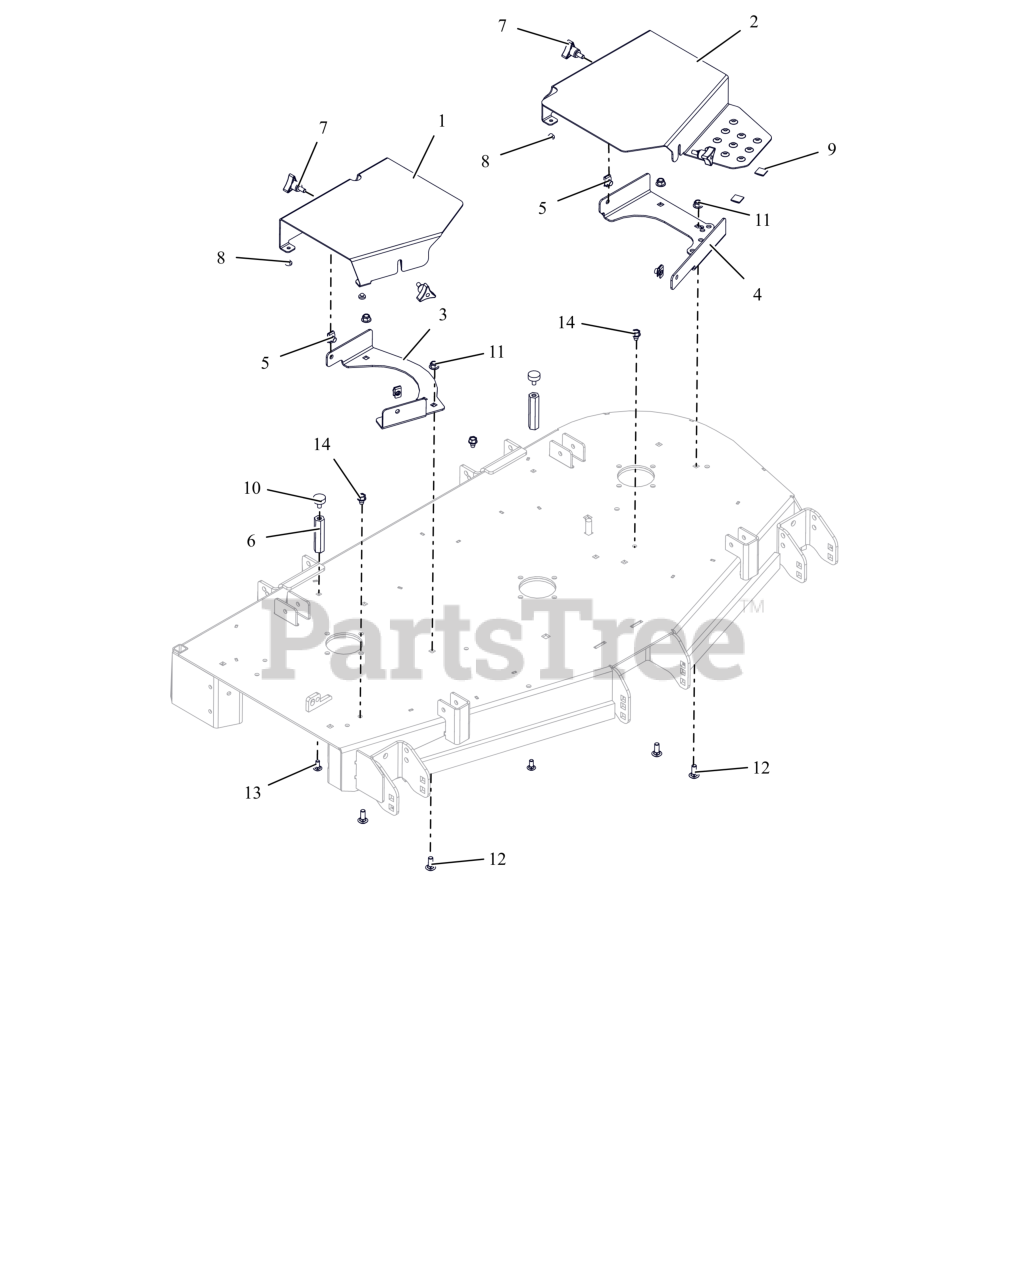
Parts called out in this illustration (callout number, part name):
1	GUARD, RH DECK - RED
2	GUARD, LH BELT - RED
3	BRKT, RH BELT GUARD MTG - RED
4	BRKT, LH BELT GUARD MTG - RED
5	NUT-CLIP RETAINER 5/16-18X.56
6	NUT, COUPLING .312-18 X 3.250
7	KNOB,WING STUD 5/16-18 X .75
8	BUMPER GROMMET
10	BUMPER, RUBBER
11	NUT,NYL-FLG .38-16 GF ZCC
12	BLT, RHSN .38-16X1.00 G5 ZCC
13	BTL,RHSN .313-18 X 0.75 G5 ZCC LT
14	SCR,TAP .375-16X.50 HWH TR ZCC
